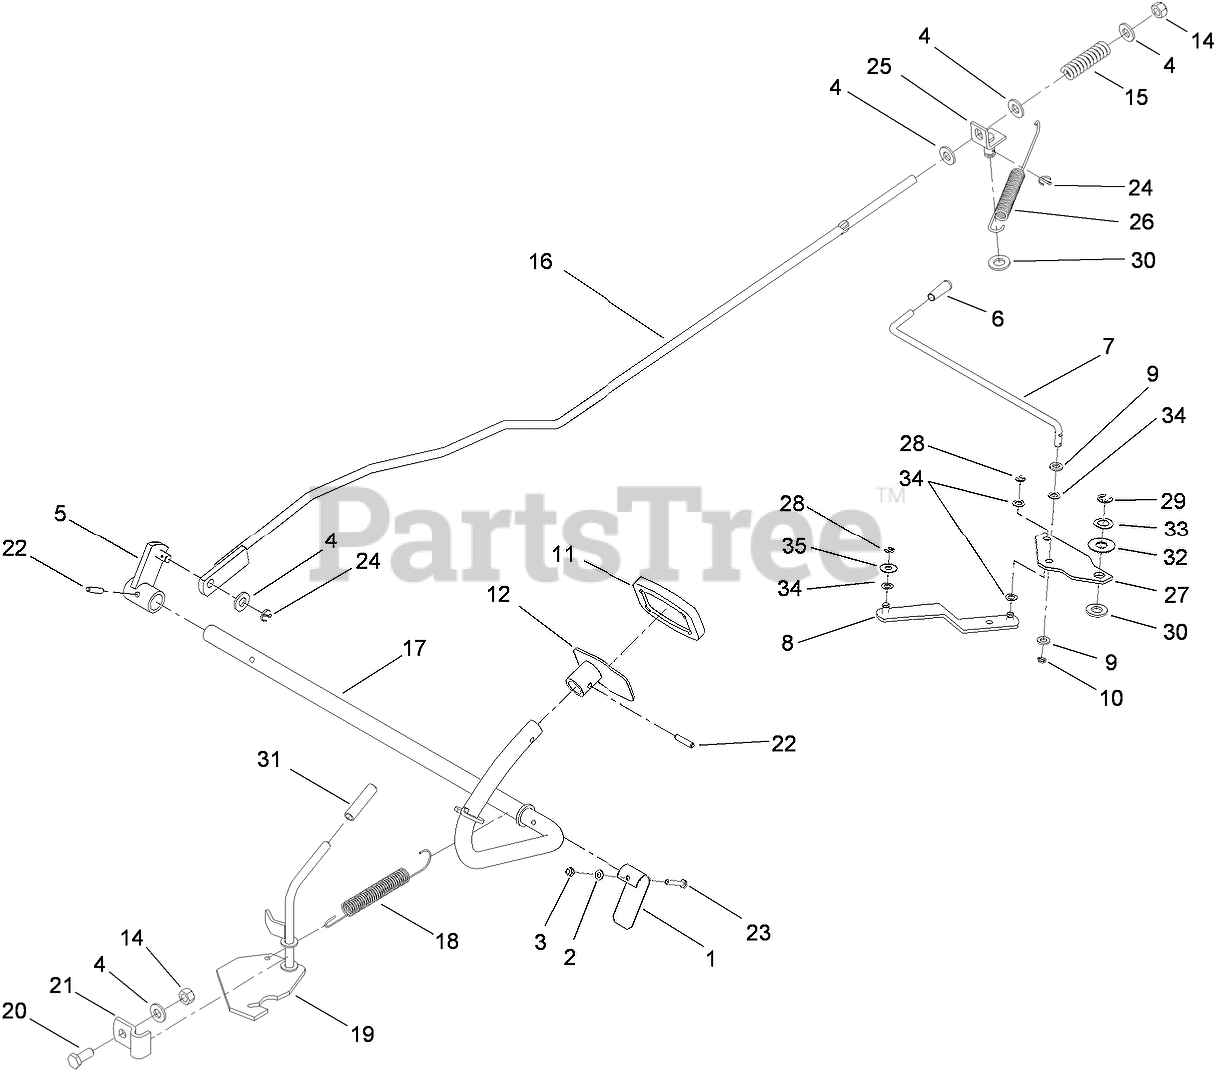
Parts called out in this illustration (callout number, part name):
1	LEVER-SPRING
2	WASHER
3	NUT-HEX
4	WASHER-PLAIN
5	BRACKET-ROD, BRAKE
6	CAP-BYPASS LEVER, HYDRO
7	ROD-LEVER, BYPASS
8	LEVER-BYPASS
9	WASHER
10	PIN-COTTER
11	PAD-PEDAL
12	PEDAL-BRAKE
14	NUT-LOCK, NI
15	SPRING-BRAKE
16	ROD-CONNECTING, BRAKE
17	SHAFT-BRAKE
18	SPRING-BRAKE, HAND
19	LEVER-BRAKE, HAND
20	SCREW-HH
21	CLAMP-LEVER, PARKING BRAKE
22	PIN-SPRING
23	SCREW-HEX
24	PIN-COTTER
25	BRACKET-ROD, BRAKE
26	SPRING
27	Plate-Bypass
28	STIRRUP
29	E-CLIP
30	WASHER-FLAT
32	Washer
33	Washer
34	Washer
35	Washer
